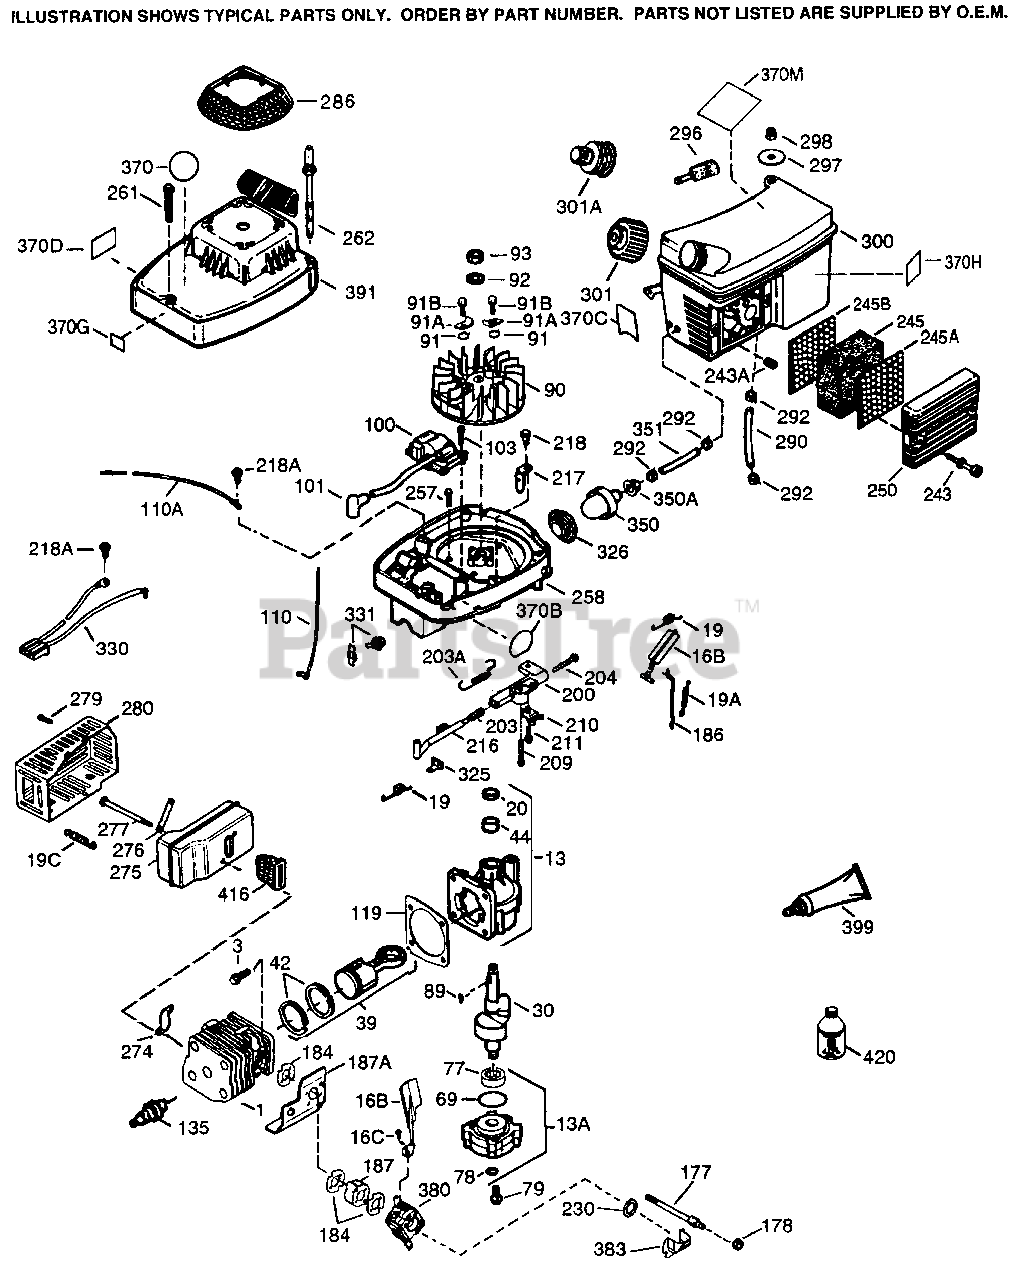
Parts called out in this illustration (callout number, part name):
1	"Cylinder (Incl. 119, 184, 187 & 187A)
3	Screw, Torx T-30, 1/4-20 x 43/64"
13	Crankcase Ass'y. (Incl. 20, 44 & 69)
13A	Crankcase Cover Ass'y.
16B	Air Vane
16C	Screw, Torx T-8, 3-48 x 7/32"
19	Governor Spring
19C	Heat Shield Spring
20	Oil Seal
30	Crankshaft
39	Piston & Rod Ass'y. (Incl. 42)
42	Ring Set
44	Cartridge Bearing
69	"O" Ring
77	Ball Bearing
78	Oil Seal
79	Screw, 1/4-20 x 3/4"
89	Flywheel Key
90	Flywheel
91	Pawl Spring
91A	Starter Pawl
91B	Screw, 12-24 x 11/64"
92	Belleville Washer
93	Flywheel Nut
100	Solid State Ignition (Incl. 101)
101	Spark Plug Cover
103	Screw, Torx T-15, 10-24 x 15/16"
110	Ground Wire
110A	Ground Wire
119	Cylinder Head Gasket
135	Resistor Spark Plug (RCJ6Y)
177	Carburetor Mounting Stud
178	Lock Nut, 10-24
184	Carburetor Gasket
187A	Air Baffle (Incl. 184 & 187)
200	Speed Control Body
203	Compression Spring
204	Screw, 8-32 x 1"
209	Screw, 8-32 x 1"
210	Conduit Clip
211	Screw, 10-32 x 1/2"
216	R.P.M. Adjusting Lever
218A	Screw, 8-32 x 1/2"
230	"O" Ring
243	Screw, 10-32 x 29/32"
243A	Thread Insert
245	Air Filter (Poly) (also available in Packaged Part #740097 (incl. 450255 & 450257))
245A	Air Filter
245B	Air Filter (Flocked Screen)
250	Air Cleaner Cover
257	Screw, 10-24 x 1/2"
258	Blower Housing Base
261	Screw, 8-32 x 1-9/16"
274	Exhaust Gasket
275	Muffler (Incl. 274 & 277)
277	Screw, 1/4-20 x 2.409"
279	Screw, 8-32 x 25/64"
280	Heat Shield
290	Fuel Line
292	Fuel Line Clamp
298	Lock Nut, 8-32
300	Fuel Tank & Primer Assembly Incl. 290 ,292,298,301,350,350A & 370C
301	Fuel Cap
326	Blower Housing Plug
350	Primer Assembly
351	Primer Line
370C	Primer Decal
370D	Caution Decal
370G	Instruction Decal
380	Carburetor (Incl. 184)
391	Rewind Starter & Housing Ass'y.
